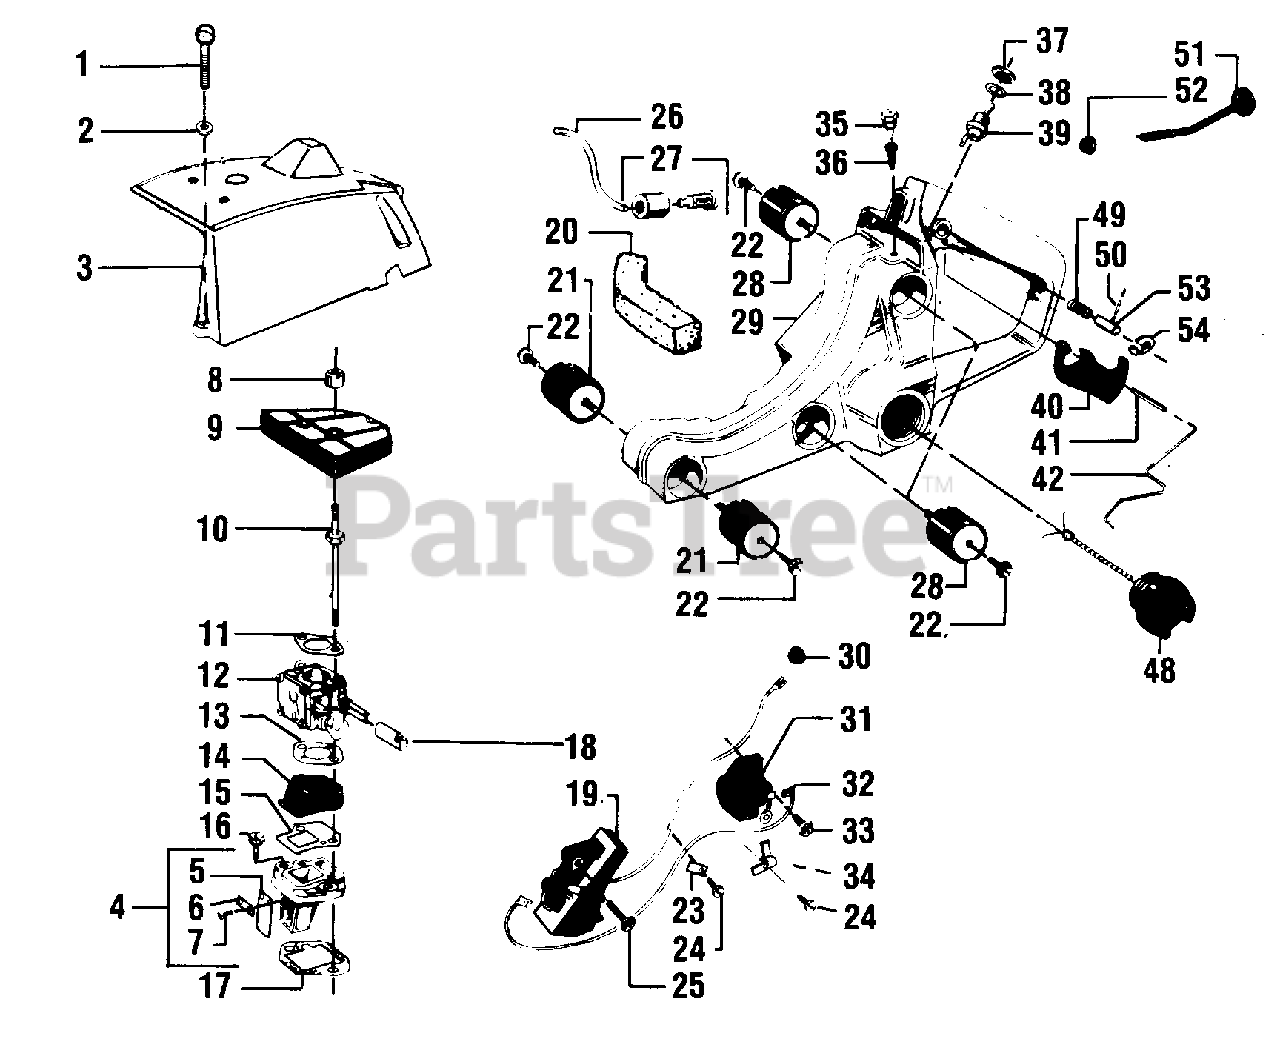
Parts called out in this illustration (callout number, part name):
1	Screw - Cylinder Carb. Cover #10 x 24
2	Washer - #10 Heavy Lock
3	Cover - Cylinder & Carburetor
4	Reed Valve Ass'y. (Incl. #5, 6 & 7)
6	Stop - Reed
7	Screw - Reed Mounting #4 - 40 x 18 Pan Head
8	Nut - Air Filter
9	Air Filter Assembly
10	Stud - Carburetor
11	Plate - Air Filter
12	Carburetor Assembly -
13	Gasket - Carburetor to Adaptor Included in Kit - Engine Gasket 69180
14	Adaptor - Carburetor
15	Gasket - Carb. Adaptor to Reed Valve Ass'y incl in Kit - Engine Gasket 69180
16	Screw - Reed Valve Assembly - 1 - 24 x 3/4
17	Gasket - Reed Valve Ass'y. Carb. Included in Kit - Engine Gasket 69180
18	Grommet - Carb. Adj. Screws
19	Module - Ignition (Incl. #30 & 32)
20	Seal - Sawdust Included in Kit - Engine Gasket 69180
21	Mount Forward Isolator (Hourglass Shape)
22	Screw - Crankcase to Mounts - 10 - 24 x 1/2
23	Clamp - Lead Wire Ignition
24	Screw - 8 - 32 x 5/16 - Tapping
25	Screw - Module Ignition - 10 - 24 x 7/8
26	Line - Fuel Pick-up (Bulk No. 8136)
27	Fuel Pick-up Assembly
28	Mount - Center and Rear Isolator (Cylindrical Shape)
29	Fuel Tank & Handle Ass'y. (Incl.#20, 48, 49, 52 & 53)
30	Grommet - Lead Wire Included in Kit - Engine Gasket 69180
31	Transformer Ass'y. (Incl.#59 on Pg. 1)
32	Lead Wire - Module to Transformer
33	Screw - 10 - 24 x 3/4 Hex Washer Hd. - Transformer
34	Clamp Lead Wire
35	Vent - Assembly - Fuel Tank (Incl. #35)
36	Check Valve - Fuel Tank Vent
37	Nut - Switch Mounting
38	Lockwasher - Switch Mounting
39	Switch - Ignition
40	Trigger - Throttle
41	Pin - Trigger
42	Wire - Throttle
48	Fuel Cap Ass'y. (Incl. "O" Ring)
49	Spring - Throttle Lock
50	Pin - Throttle Lock
51	Choke Knob
52	Grommet - Choke Rod Included in Kit - Engine Gasket 69180
53	Sleeve - Throttle Lock
54	"E" Ring - Throttle Lock
